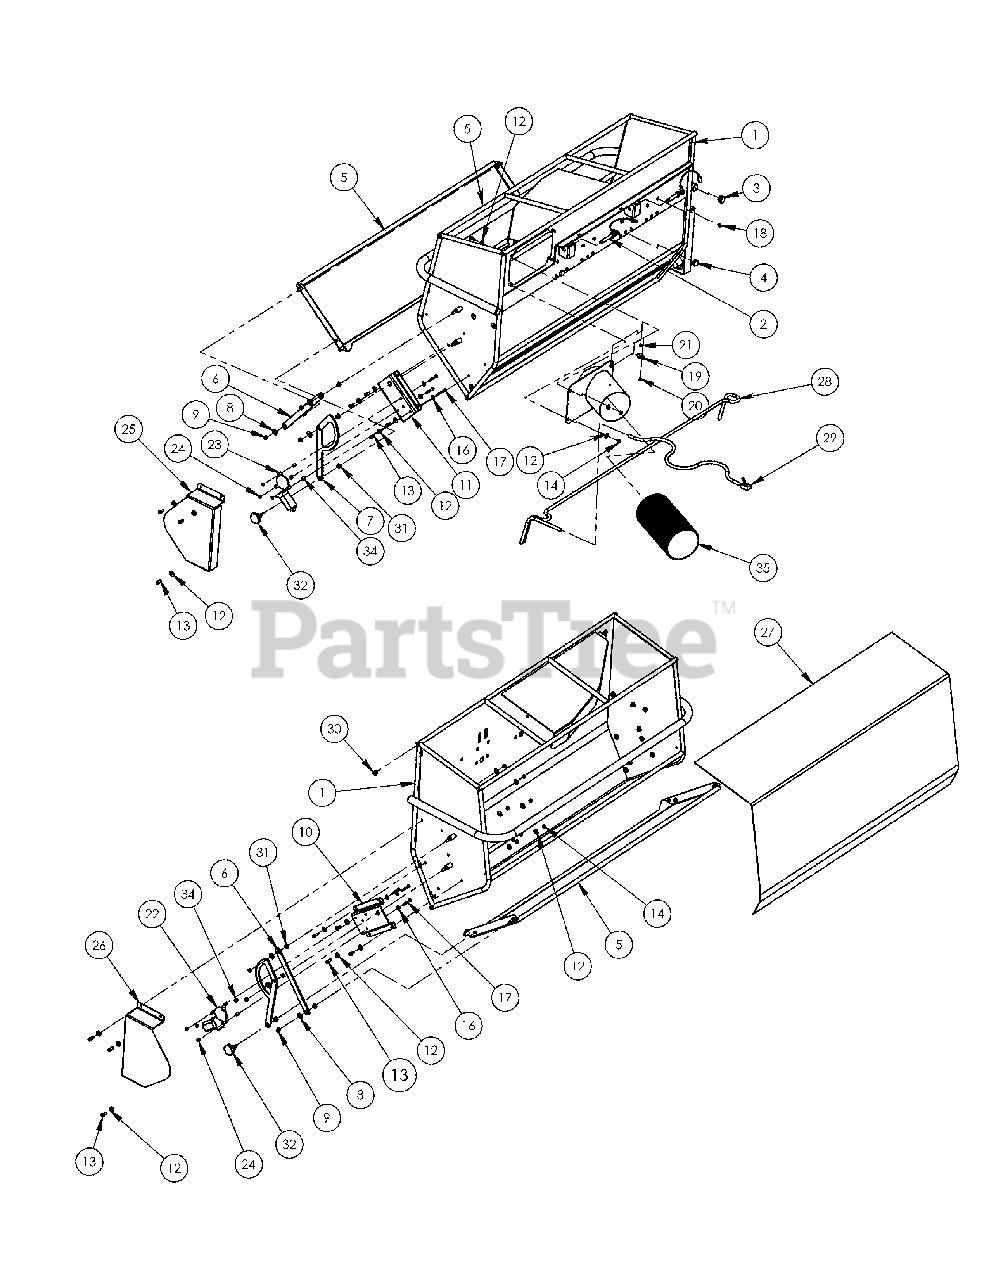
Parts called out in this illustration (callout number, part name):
1	DEDICATED DUMP FRAME 54"
2	1/2 DETENT PIN 2.5" LONG
3	1.25" HOLE PLUG, PLASTIC
4	RUBBER BUMPER
5	GATE ASSEMBLY
6	MASTER LINK
7	DFS ELECTRIC DRIVE RING-GEAR
8	3/8 Washer SAE
9	3/8-16 NYLOCK NUT
10	MOTOR ADAPTER PLATE
11	MOTOR ADAPTER PLATE
12	5/16" Flat Washer
13	CAP SCREW 5/16-18 x .75
14	5/16-18 Nylon Insert Nut
15	6" 3-BAG INLET TUBE
16	1/4" USS WASHER
17	CAP SCREW 1/4-20 x 1 3/4
18	PLUG, HOLE 7/16
19	SPRING CLIP
20	#10 x 3/4 SCREW
21	#10-24 Nylon Insert Nut
22	ELETRIC MOTOR, LEFT HAND
23	ELETRIC MOTOR, RIGHT HAND
24	1/4-20 Nylon Insert Nut
25	DFS MOTOR GUARD, Right
26	DFS MOTOR GUARD, Left
27	DDFS FABRIC COVERING
28	DFS 3-BAG WIRING HARNESS
29	DFS IMPLEMENT WIRING HARNESS
30	3/4" HOLE PLUG, PLASTIC
31	PLASTIC FLANGE BUSHING, 1/2"ID x 5/8" OD
32	DFS Release Knob
33	BUSHING, 1/2" OD x 3/8" ID x 1/2"Lg.
34	MOTOR OFFSET BOSS
